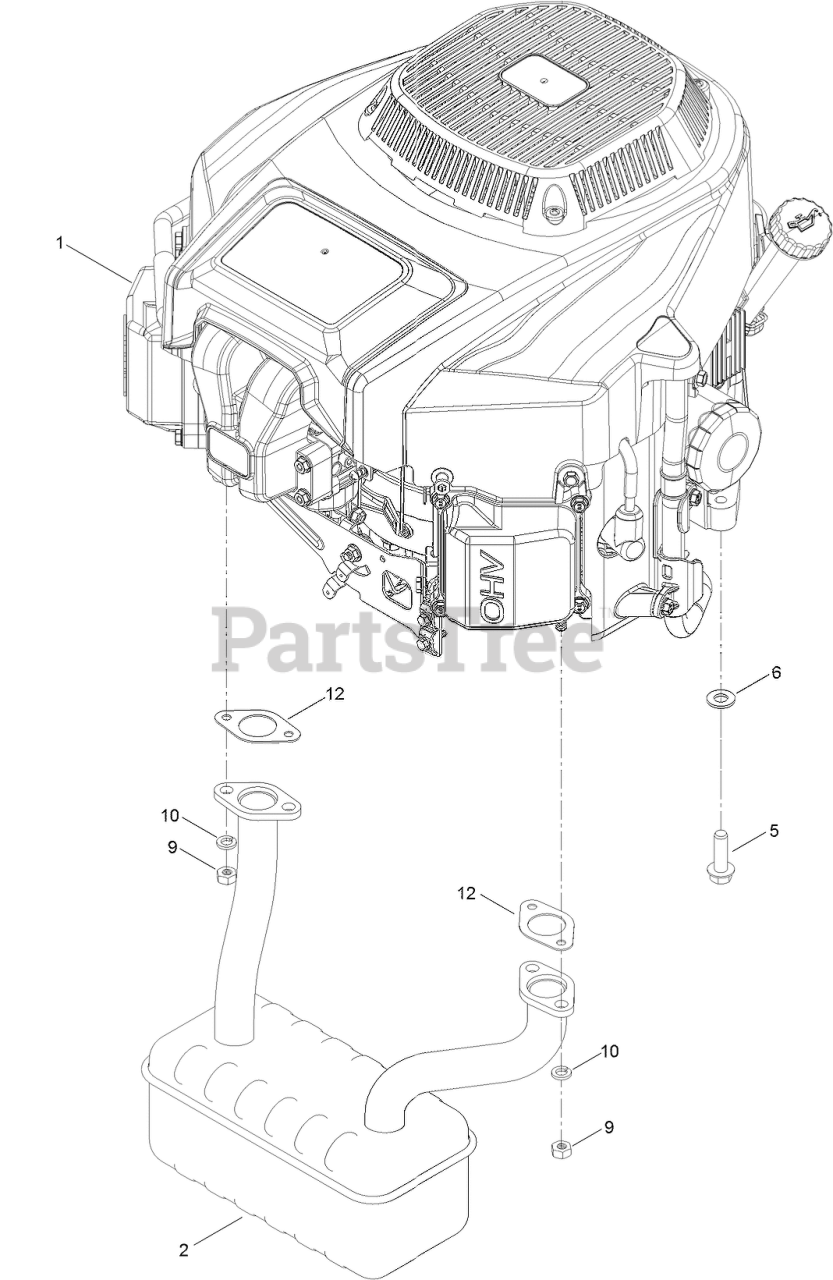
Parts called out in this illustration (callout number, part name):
1	ENGINE-2P77F
2	MUFFLER
5	SCREW-THD
6	WASHER-FLAT
9	NUT-HH
10	WASHER-LOCK, SPLIT
12	GASKET-EXHAUST
